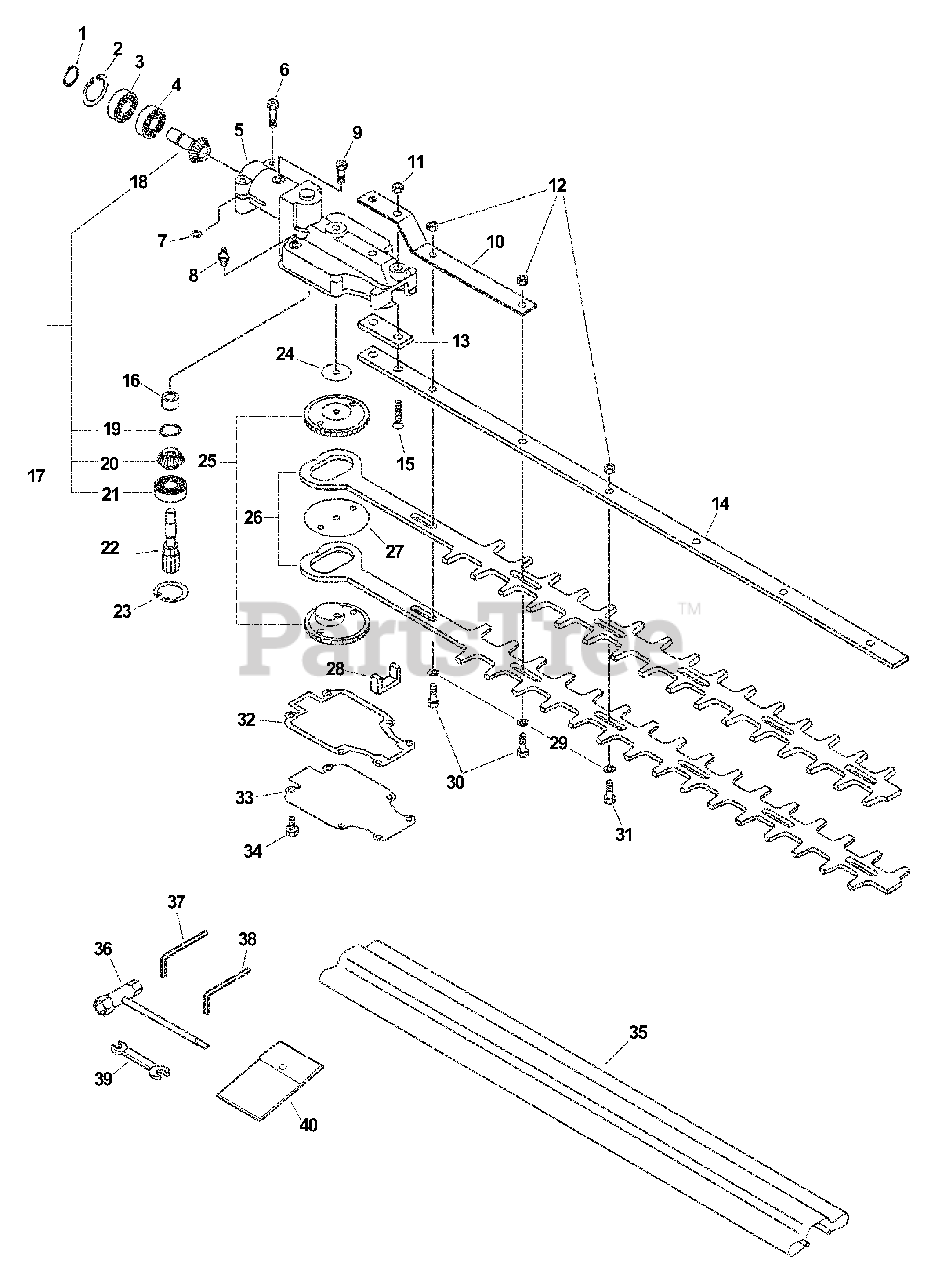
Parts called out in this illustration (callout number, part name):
1	RING, RETAINING Ø24
2	RING, SNAP Ø12
3	BEARING, BALL 6901Z
4	BEARING, BALL 6901
5	CASE, GEAR - UPPER
6	BOLT 5×28
8	FITTING, GREASE
9	BOLT 5×12
10	PLATE, ANGLE
11	NUT, HEX M6
13	SPACER
14	BAR, FRAME
15	SCREW 6×35
16	BEARING, NEEDLE
17	SPUR GEAR ASSY
18	GEAR, BEVEL - DRIVEN
19	RING, RETAINING
20	GEAR, BEVEL - DRIVEN
21	BEARING, BALL 6901
22	GEAR, PINION
23	RING, RETAINING Ø24
24	WASHER 6.5×30×0.2
25	GEAR, SPUR
26	BLADE, TRIMMER
27	WASHER 6.7×54×0.38
28	PACKING, FELT
29	WASHER 6.5×15.5×0.6
30	BOLT 6×20
32	GASKET, GEAR CASE
33	LID, GEAR CASE
34	BOLT 4×12
35	COVER, BLADE
36	T-WRENCH 17x-19 L200
37	WRENCH, ALLEN 4 MM
38	WRENCH, ALLEN 3 MM
39	SPANNER 8×10
40	BAG, TOOL
